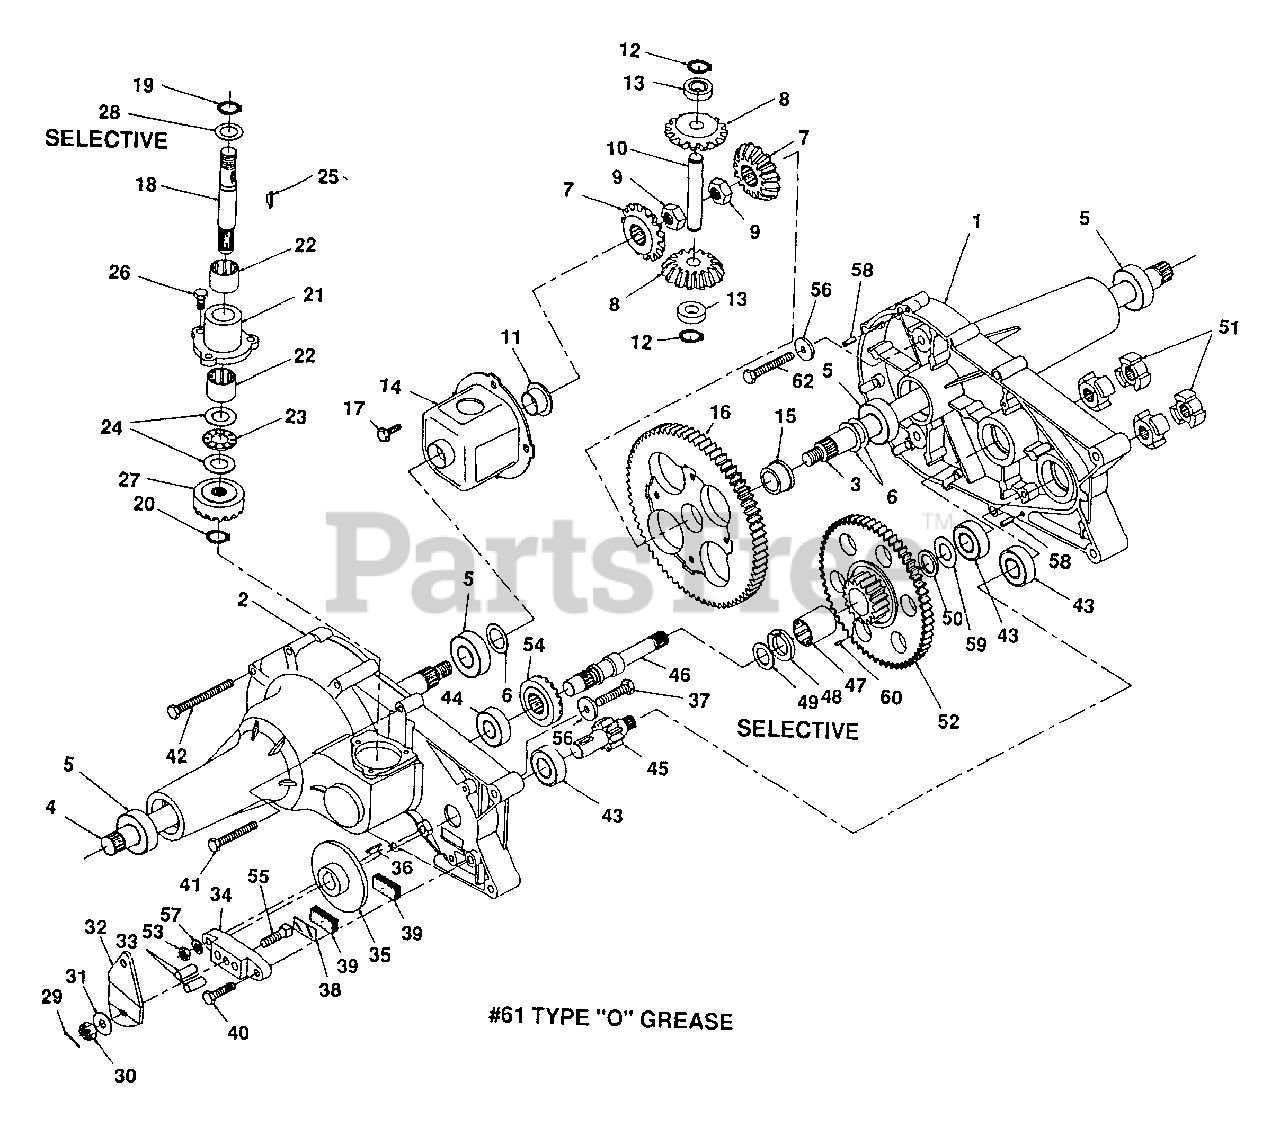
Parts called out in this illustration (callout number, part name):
1	HOUSING HALF L.H.
2	HOUSING HALF RH
5	BEARING, BALL 3/4ID X 40MM OD X 12 MM
6	WASHER, FLAT 3/4ID X 1-1/8OD X .025 THK
7	GEAR, MITER
8	GEAR, MITER
10	SHAFT, CROSS
11	BEARING, FL 3/4 ID X 7/8 OD
12	SNAP RING
13	BEARING, THRUST
14	HOUSING
15	BEARING, FLANGE
16	GEAR, DIFFERENTIAL 72 TOOTH
17	LOCKING BOLT, 1/4-28 X 9/16" LG
18	SHAFT, INPUT
19	RETAINING, RING
20	RING, RETAINING
21	HOUSING, INPUT BEARING
22	BEARING, NEEDLE
23	BEARING, THRUST
24	THRUST RACE
25	KEY, HI-PRO 3/32 X 5/8 DIA.
26	SCREW, HEX W/PATCH 1/4-20 X 3/4 LONG
27	GEAR, INPUT PINION 17 TOOTH
28	WASHER, FLAT .62ID X 1.0 OD X .050 THK.
28	WASHER, FLAT .62ID X 1.0 OD X .040 THK.
29	PIN, COTTER
30	NUT, CASTLE 5/16-24
31	WASHER, FLAT .343ID X .88OD X .062 THK.
32	ARM, BRAKE ACTUATOR
33	PIN, BRAKE ACTUATING
34	BRAKE, YOKE
35	DISC, BRAKE
36	KEY, HI-PRO 3/16 X 5/8" DIA.
37	BOLT, HEX 1/4-20 X 1.50 LONG
38	PLATE, PUCK
39	PUCK, BRAKE
40	BOLT, HEX W/PATCH 1/4-20 X 1.00 LG
41	BOLT, HEX SELF-TAP 1/4-20 X 2.00 LG
42	BOLT, HEX SELF-TAP 1/4-20 X 3.00 LG
43	BEARING, BALL
44	BEARING, BALL
45	SHAFT, PINION W/11 TOOTH GEAR
46	SHAFT, DRIVE
47	BEARING, NEEDLE
48	BRONZE THRUST BRG 5/8ID X 1-1/4OD X 7/64 THK.
49	WASHER, FLAT.62ID X 1.0 OD X .050 THK.
49	WASHER, FLAT.62ID X 1.0 OD X .040 THK.
50	GREASE, SEAL BRONZE
51	COUPLING
52	GEAR, 60 AND 17 TOOTH
53	NUT, HEX 1/4-20
54	GEAR, DRIVE PINION 17 T.
55	BOLT, SQUARE HEAD
56	WASHER, 7/8OD X .265ID X .125 THK.
57	WASHER, 1/4" SPRING LOCK
58	PIN, ROLL 3/16" DIA X 1/2" LG
59	WASHER, FLAT .62ID X 1.0 OD X .030 THK.
61	TYPE "O" GREASE (10 OZ. TUBE)
62	BOLT, HEX SELF TAP 1/4-20 X 2-1/2
